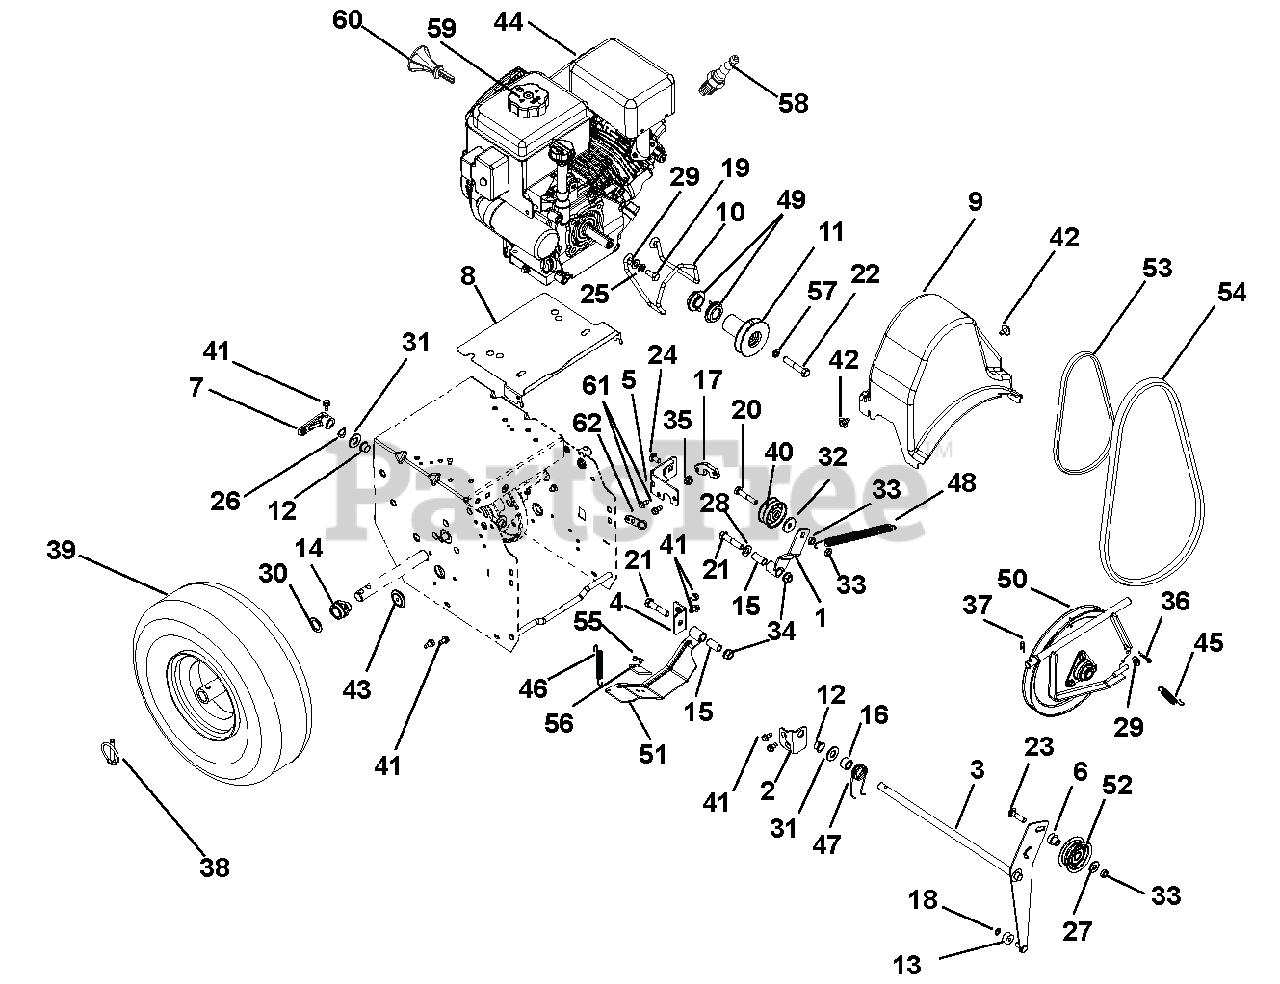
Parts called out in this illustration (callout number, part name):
1	ARM, TRACTION IDLER
2	BRACKET, MOUNT - IDLER ARM
3	WELDMENT, ATTACHMENT IDLER ARM
4	BRACKET, MOUNT - BRAKE
5	WELDMENT, FRAME BRACKET
6	SPCR, BRG .315X.50X.688X.281
7	ARM, CLUTCH - ATTACHMENT
8	BAFFLE,ENGINE,SMALL BLOCK
9	COVER, COMPACT BELT
10	FINGER, BELT
10	BELT FINGER
11	SHEAVE, AUGER - COMPACT
11	SHEAVE,AUGER 3/4" PM
11	SHEAVE, ATTACHMENT DRIVE
11	SHEAVE, AUGER DRIVE
12	BUSHING, POLYLINER-.50 SPLIT
13	BSHG,SLV .265 X .625 X .375
14	BSHG .75X1.125X.65
15	BSHG-SLV .385X.500X1.045
16	BSHG-SLV .510X.751X.475
17	SPACER, SWING GATE
18	RG-RTNG-EXT .250X.010
19	BLT-HEX .31-24X.75 YWZC GR5
20	@BLT-HEX .31-18X1.75 GR5 YWZC
21	@BLT-HEX .38-16X1.75 GR5 YWZC
22	BLT-HEX .38-24X2.0 YWZC
23	BLT-RDHDSQSHNK.31-18X1.13 G5YZ
24	@BLT-RHDSSQNK .31-18X.62 G5YZ
25	WSHR-LK .312X.097 HVY YWZC
26	WSHR-WAVE .50X.75X.015 .13FRHT
27	@WSHR-FL-STL.38X.875X.083 YWZC
28	@WSHR-FL-STL.406X.812X.065 YWZ
29	@WSHR-FL-STL.344X.688X.065YWZC
30	WSHR-FL-STL.754X1.125X.062YWZC
30	BSHG-SLV .75X1.12X1.062 NYL BK
31	@WSHR-FL-STL.531X1.06X.095YWZC
32	WSHR-FL-STL .344X1.125X.135
33	@NUT-LK-CTR-JAM .31-18 YWZC
34	@NUT-LK-TOP-FLG .38-16 YWZC
35	@NUT-LK-TOP-FLG .31-18 YWZC
36	PIN-HAIR INT .08X.18X1.18 YWZC
37	CLIP, SPRING
38	PIN-LOK .31X1.75
39	TIRE/WHEEL, 15X5.00-6 K398A
39	TIRE, 15" K398A
39	TIRE/WHEEL, 13X4.10-6 K398A
39	TIRE, 13" K398A
40	IDLER,1.875" OD
41	SCR-TAP .25-20X.50 HWH TR YWZ
42	SCR-TAP .25-20X.5 CAPTIVE
43	PLUG, HOLE - 1.00" FLEXTEMP
44	ENGINE, SNO-TEK 208 120V
44	ENGINE,LCT STORMFORCE 208 240V
44	ENGINE, SNO-TEK 136 240V
45	SPRING, EXT. .043X.438X1.64
46	SPRING-EXT .437 X .438 X 2.64
47	SG-TORS .075 X .955
48	SPRING, EXTENSION
49	TRACTION SHEAVE HALF
49	SHEAVE, TRACTION
50	PLATE, SWING - ASSEMBLY
51	BRAKE ARM W/PAD
52	IDLER
53	V-BELT, 3L-WRAPPED
54	V-BELT, HA-RAW EDGE
55	RVT-POP .187 YZ
56	PAD, BRAKE
57	@WSHR-LK .38X.094 REG YWZC
58	PLUG, SPARK
59	CAP, FUEL TANK BLACK
60	KEY, PUSH/PULL LCT (2/PACKAGE)
61	SCR-TAP-PM .25-20X.75 TR YWZ
62	SUPPORT BUSHING, SWING GATE
